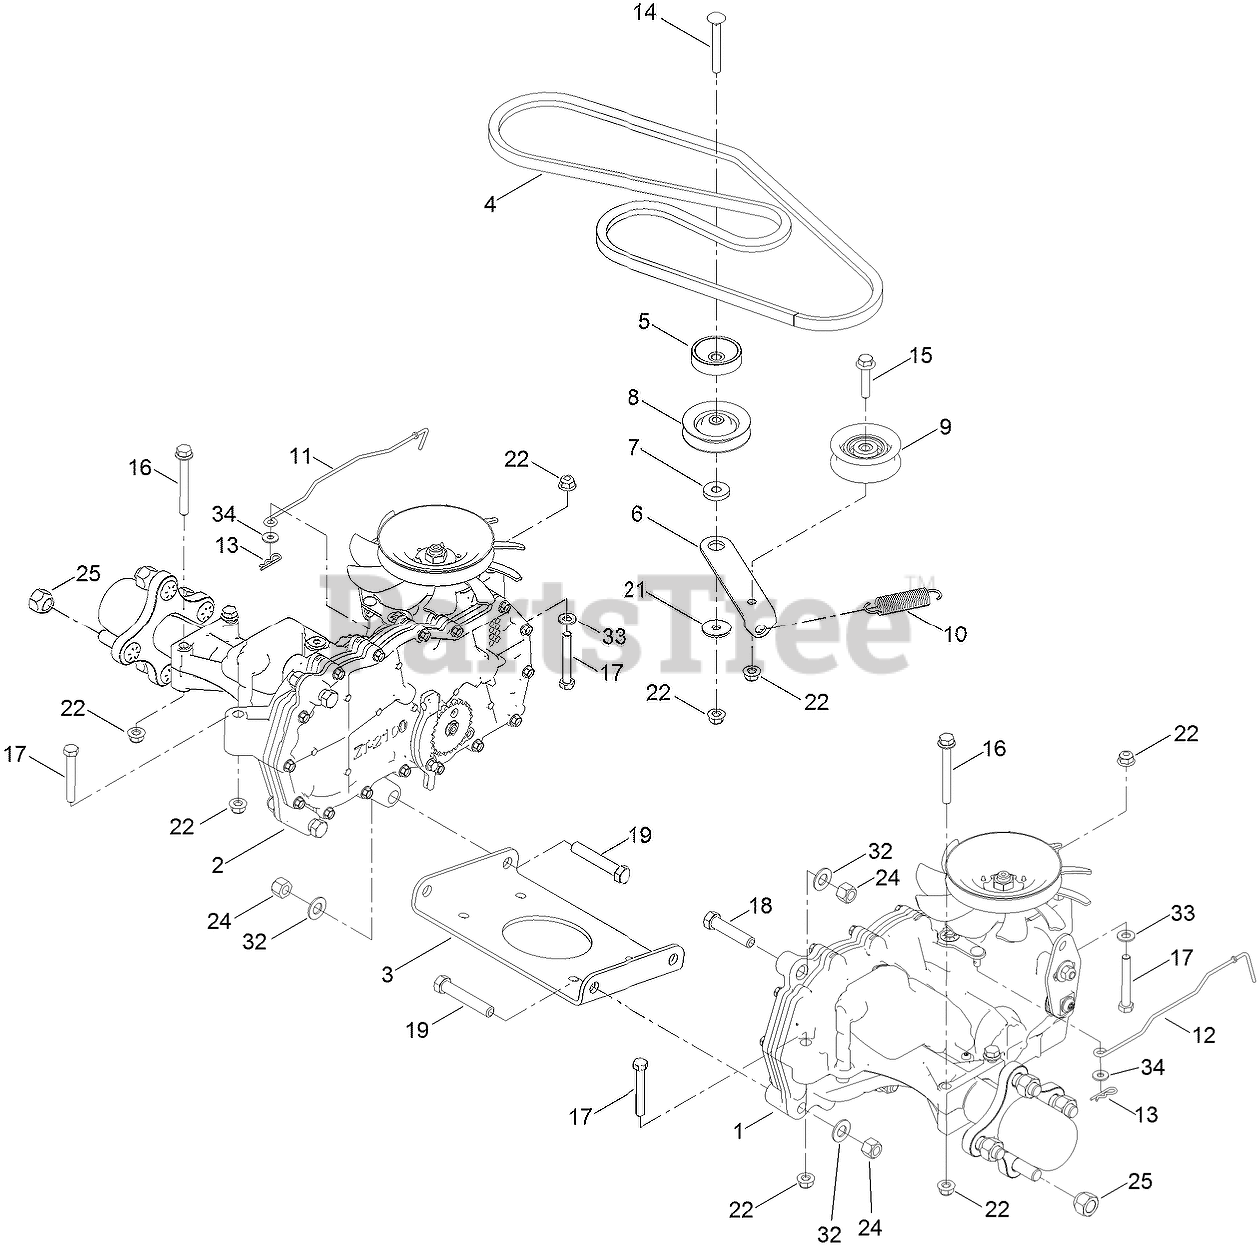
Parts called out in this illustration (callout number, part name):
1	LH HYDRO TRANSAXLE ASM
2	RH HYDRO TRANSAXLE ASM
3	CROSSPLATE-HYDRO
4	V-BELT
5	SPACER
6	ARM-IDLER
7	SPACER-IDLER ARM
9	PULLEY-IDLER, FLAT
10	SPRING-PEDAL, RETURN
11	ROD-BYPASS, RH
12	ROD-BYPASS, LH
14	SCREW-CARR
15	SCREW-HHF
16	SCREW-HHF
17	SCREW-HH
18	SCREW-HH
19	SCREW-HH
21	WASHER-PIVOT
22	NUT-HF, NI
24	NUT-LOCK, NI
25	NUT-LUG
32	WASHER-FLAT
33	WASHER-PLAIN
34	WASHER
